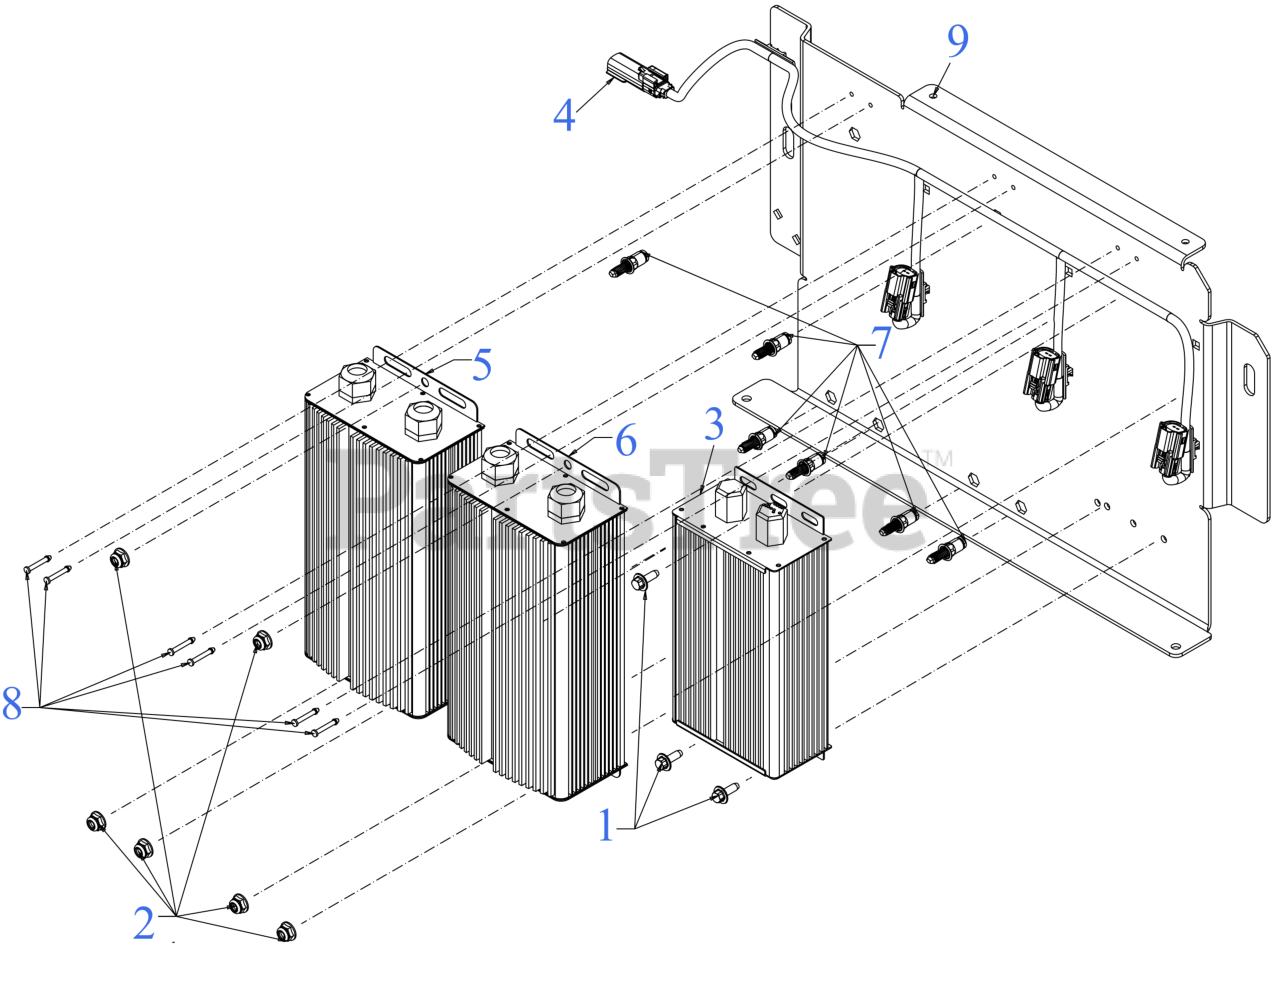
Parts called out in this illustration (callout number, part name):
1	SCREW M6-1 x .625
2	FLANGE LOCK NUT
3	MOTOR CONTROL (L TRAC)
4	CANBUS HARNESS
5	DECK MOTOR CONTROLLER (LH)
6	DECK MOTOR CONTROLLER (RH)
7	RIVET-HEX STUD 1/4-20 FRM
8	PANEL RATCHET CLIP .125 x .750
9	CONTOL MOUNT BRACKET
